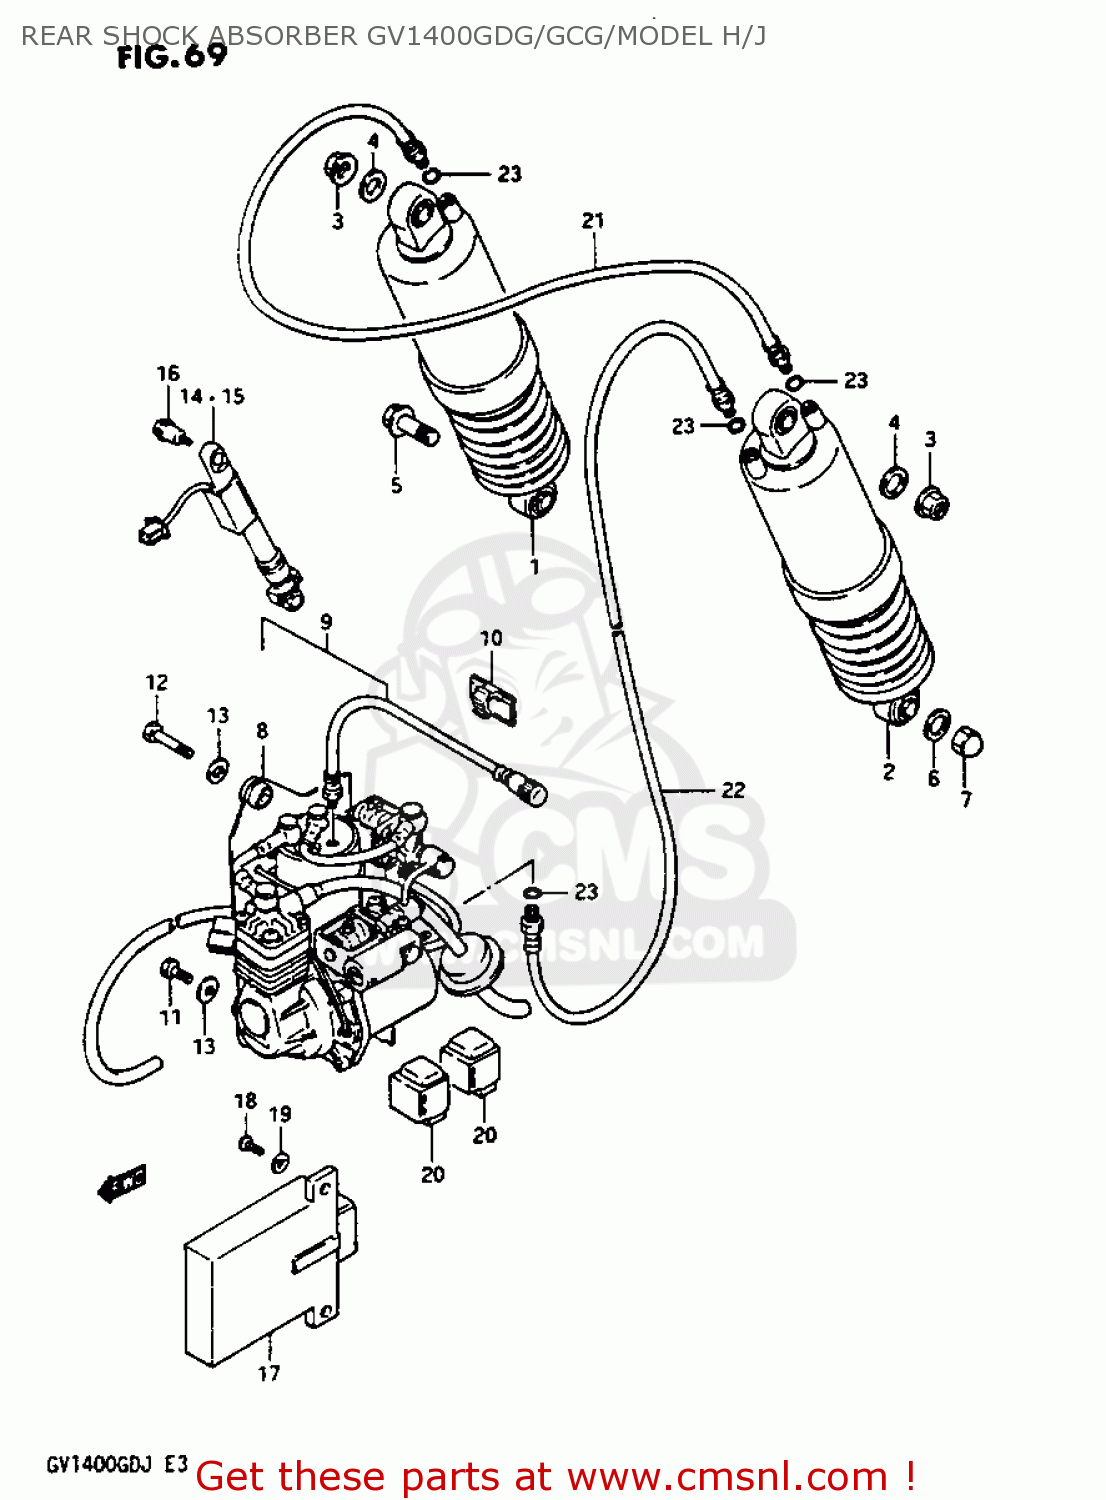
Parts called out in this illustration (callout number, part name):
1	ABSORBER ASSY,RR SHOCK,R
2	ABSORBER ASSY,RR SHOCK,L
3	NUT
4	WASHER
5	BOLT 2X33
6	WASHER
7	NUT
8	AUTO LEVEL ASSEMBLY,REAR SHOCK
9	AUTO LEVEL ASSEMBLY,REAR SHOCK
10	CLAMP
11	BOLT
12	BOLT
13	WASHER (6.5X20X1.2)
14	SENSOR ASSEMBLY,AUTO LEVEL
15	SENSOR ASSEMBLY,AUTO LEVEL
16	BOLT(6X21)
17	UNIT,AUTO LEVEL CONTROL
18	SCREW
19	WASHER
20	RELAY ASSY, MARKER LAMP
21	HOSE COMP,REAR SHOCK ABSORBER
22	HOSE COMP,AUTO LEVEL
23	O RING(D:1.9,ID:5.7)
